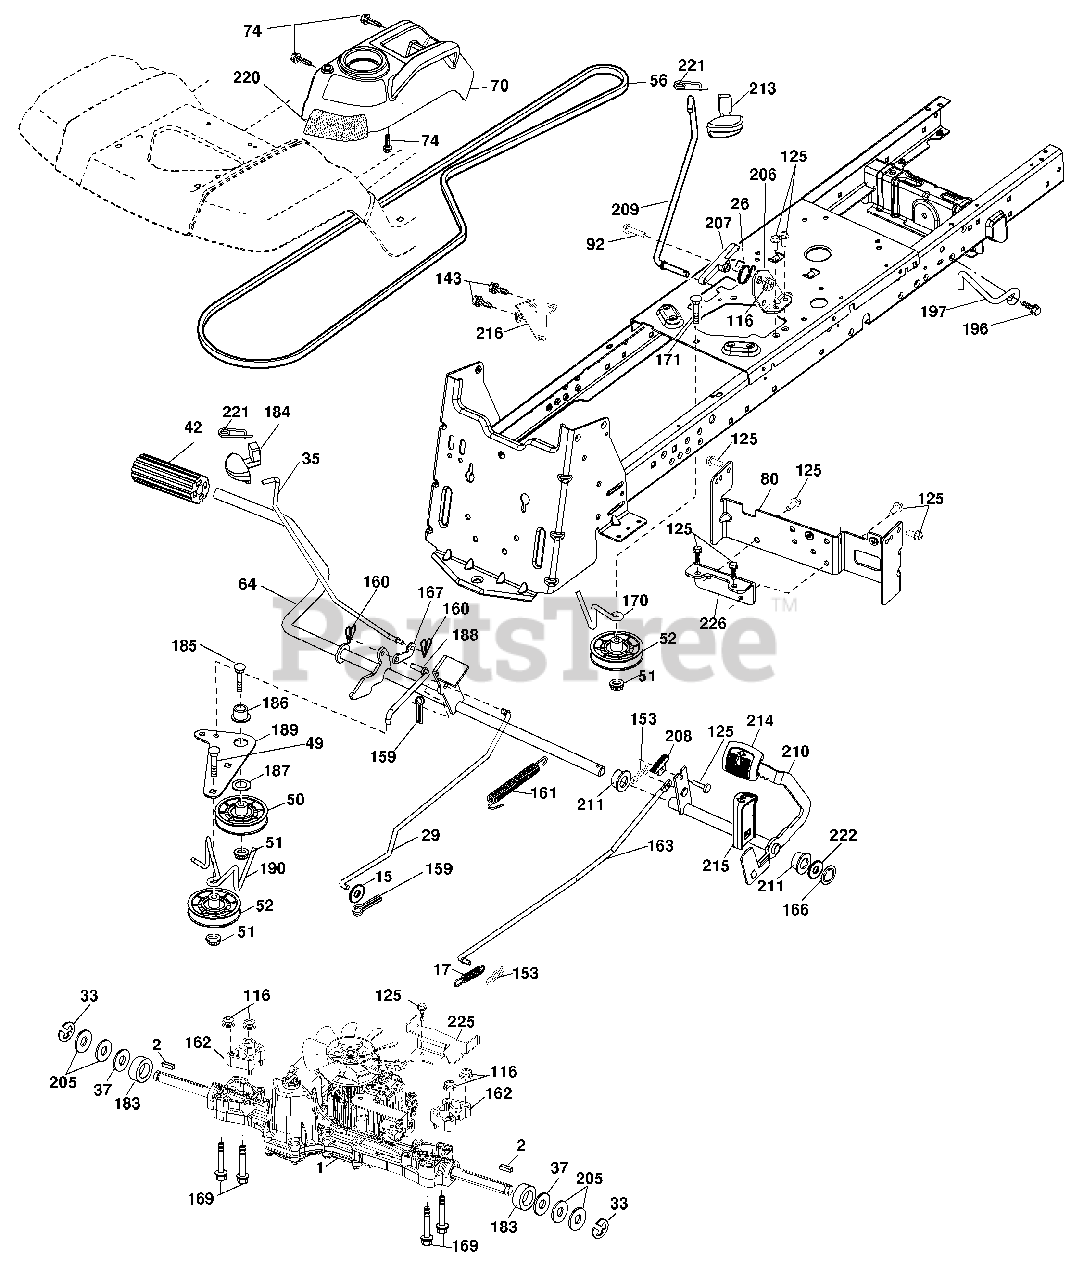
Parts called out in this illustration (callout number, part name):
1	Transaxle, TUFFTORQ K46
2	Key 1/4 x 2.5
15	Washer 13/32 x 13/16 x 16 Ga.
17	Spring, Brake
26	Spring Return Cruise
29	Rod, Brake
35	Rod, Brake, Park
37	Washer Harden
42	Cover, Foot Pedal
50	Pulley Idler Flat
51	Lock Nut 3/8-16
52	Idler V-Groove 910" Offset
56	V-Belt, Drive
64	Shaft Asm. Pedal Brake Control
70	Console Asm.
74	Screw 1/4 x 1/2
80	Strap Torque
92	Bolt Fin Hex 5/16-18 unc x 1.25
116	Nut Lock Hex Flange 5/16-18
125	Screw 5/16-18 x 3/4
143	Screw Thdrol 5/16-18 x 1/2
153	Retainer Spring
159	Pin Cotter 1/8 x 3/4
160	Retainer Clip
161	Spring, Return, Clutch
162	Spacer Transaxle
163	Rod Pedal Control
166	Nut Push .625
167	Latch Brake Parking
169	Bolt Hex Flghd 5/16-18 x 3.75
170	Keeper Belt Centerspan
171	Bolt RDHD SQNK 3/8-16UNC x 2
183	Spacer Split
184	Handle Parking Brake
185	Bolt Rdhd Sqnk 3/8-16 x 2-1/2
186	Spacer Retainer
187	Washer
188	Link Clutch Ground Drive
189	Bellcrank Ground Drive
190	Keeper Bellcrank Ground Drive
196	Screw 3/8-16 x 1
197	Bracket Clutch Anti-Rotation
206	Bracket Mount Latch Cruise
207	Latch Control Cruise
208	Gear Sector Control Cruise
209	Rod Control Cruise
210	Rocker Asm. Pedal Control
211	Bearing Nylon
213	Knob Control Cruise
214	Pedal Forward
215	Pedal Reverse
216	Bracket Pulley Idler
220	Reflector RH
221	Retainer Spring Clip Handle
222	Washer 21/32 x 1-1/4 x 10 Ga.
225	Keeper Belt Trans.
226	Bracket Mount Touque
